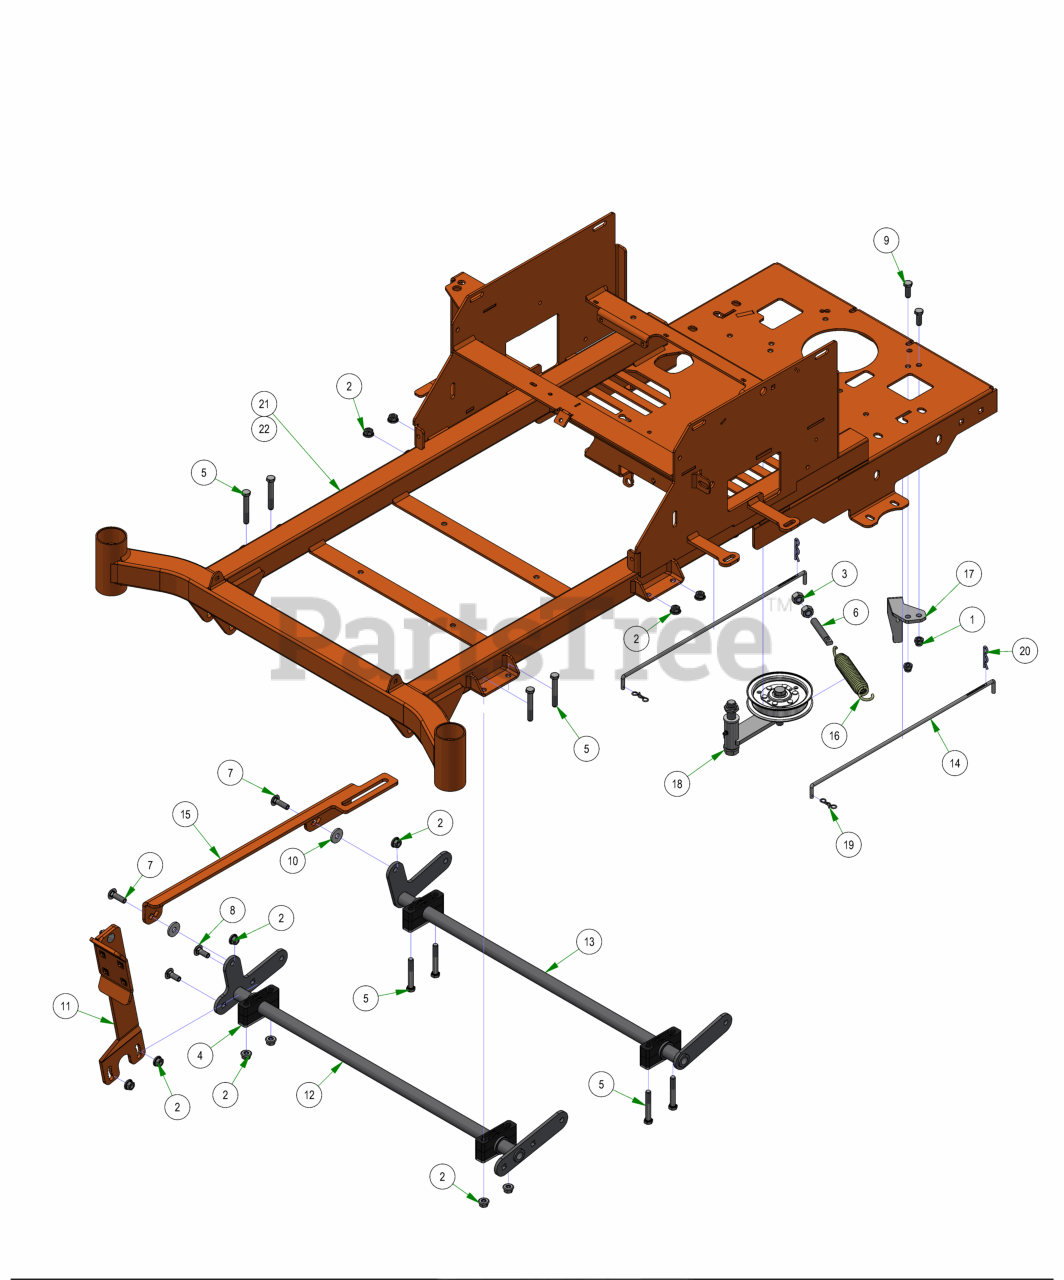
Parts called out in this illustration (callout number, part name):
1	3/8-16 NYLON INSERT LOCKNUT ZINC
2	3/8-16 NYLON INSERT FLANGE LOCKNUT (GR.F) ZINC
3	1/2-13 HEX NUT ZINC
4	Pillow Block Kit
5	3/8-16 X 2-1/2 HEX CAP SCREW (GR.5) ZINC
6	All Thread
7	3/8-16 X 1-1/4 CARRIAGE BOLT ZINC
8	3/8-16 X 1 CARRIAGE BOLT (GR.5) ZINC
9	3/8-16 X 1 GR 5 Hex Bolts Zinc
10	.390 ID X 1.12 OD X .125 THK FLAT WASHER NYLON
11	Foot Pedal Assembly
12	Actuator Bar Front- 2017 MZ/ZT
13	Actuator Bar Rear- 2017 MZ/ZT
14	Neutral Rod
15	2017 MZ/ZT Actuator Linkage
16	Deck Idler Spring
17	2025 ZT Clutch Bracket
18	ZT Pump Idler
20	Neutral Rod Clip
21	2025 MZ 42-48 Frame
22	2025 MZ-Avenger 54-60 Frame
